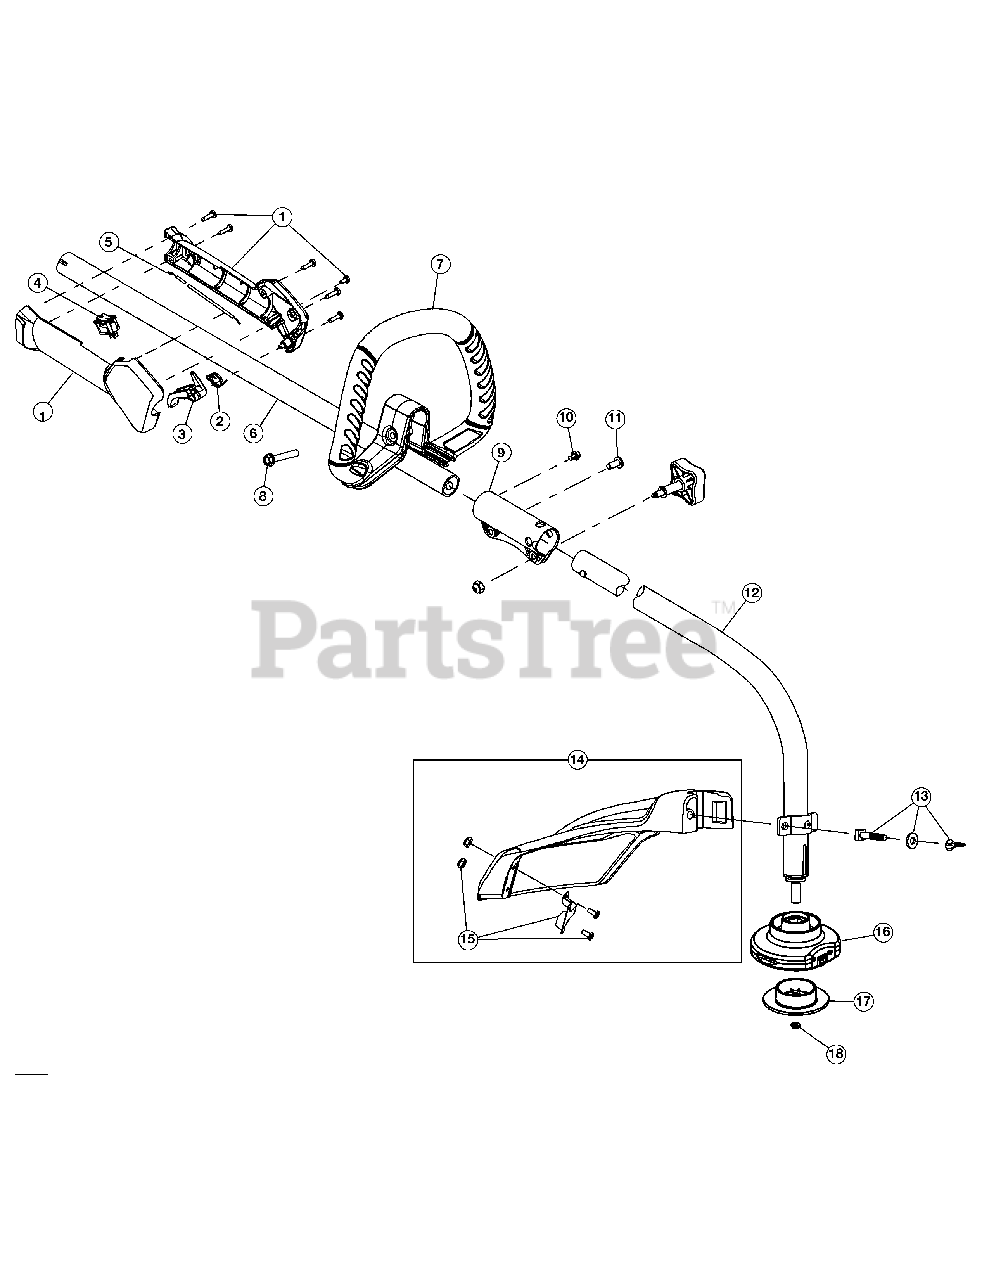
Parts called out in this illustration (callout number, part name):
1	Throttle Housing Assembly (Incl. 2 - 4)
2	Throttle Trigger Spring
3	Throttle Trigger
5	Throttle Cable Assembly
6	Upper Drive Shaft Housing Assembly
7	D-Handle Assembly (Incl. 8)
9	Split Boom Coupler (Incl. 10 and 11)
12	Lower Drive Shaft Housing Assembly
13	Shield Mounting Hardware
14	Shield Assembly (Incl. 15)
15	Blade Assembly
16	Bump Head Assembly (Incl. 17 and 18)
17	Glide Cap
18	Lock Nut
